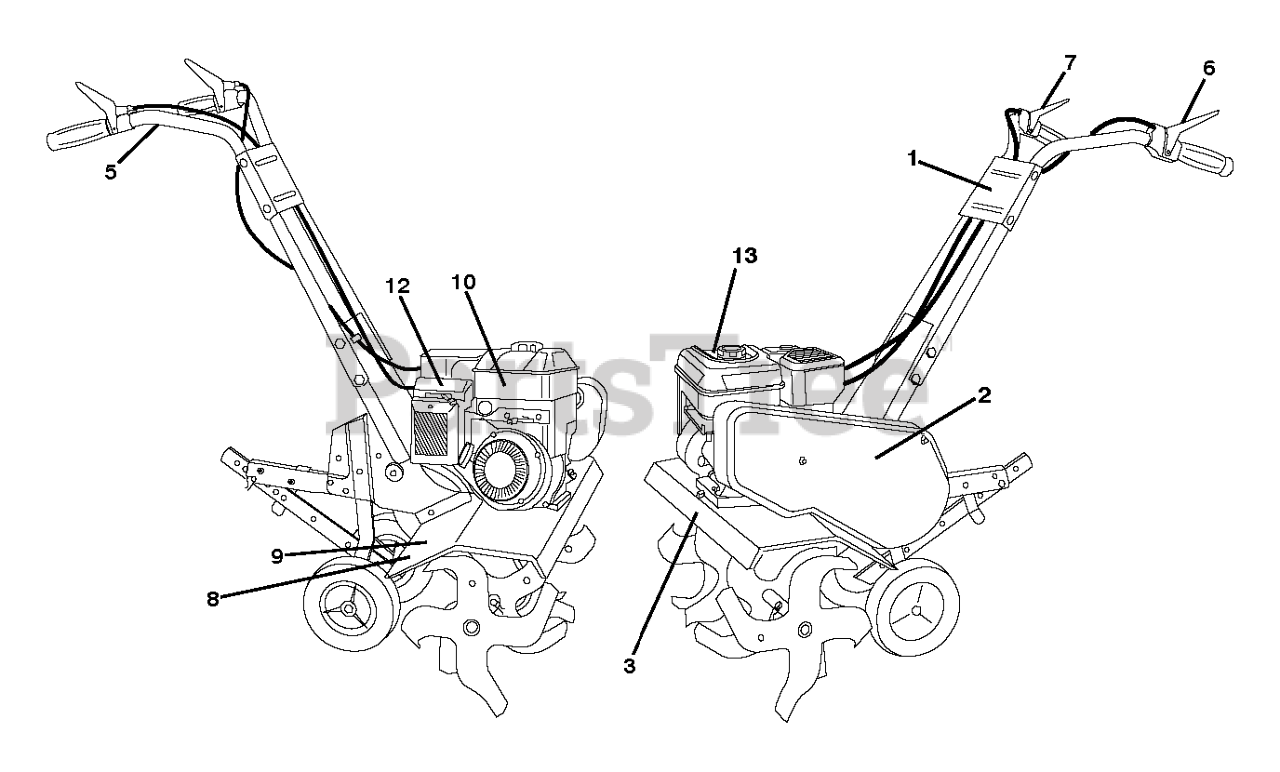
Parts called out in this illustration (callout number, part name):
1	DECAL.CONSOLE.DBBND.FT900.HUSQ
2	RP.DECAL.BADGE.170MM.TEXTLOGO
3	DECAL.TINESHIELD.FTT.26".HUSQ.
5	DECAL TI (2 2)
6	DECAL
7	DECAL
8	DECAL TI
9	DECAL.WARNING.SHLD.ENG/FR
10	DECAL.B&S.900.TANK.REF.276991
12	DECAL.B&S.900.A/S.C (279005)
13	DECAL,ETHANOL E85 WARNING
